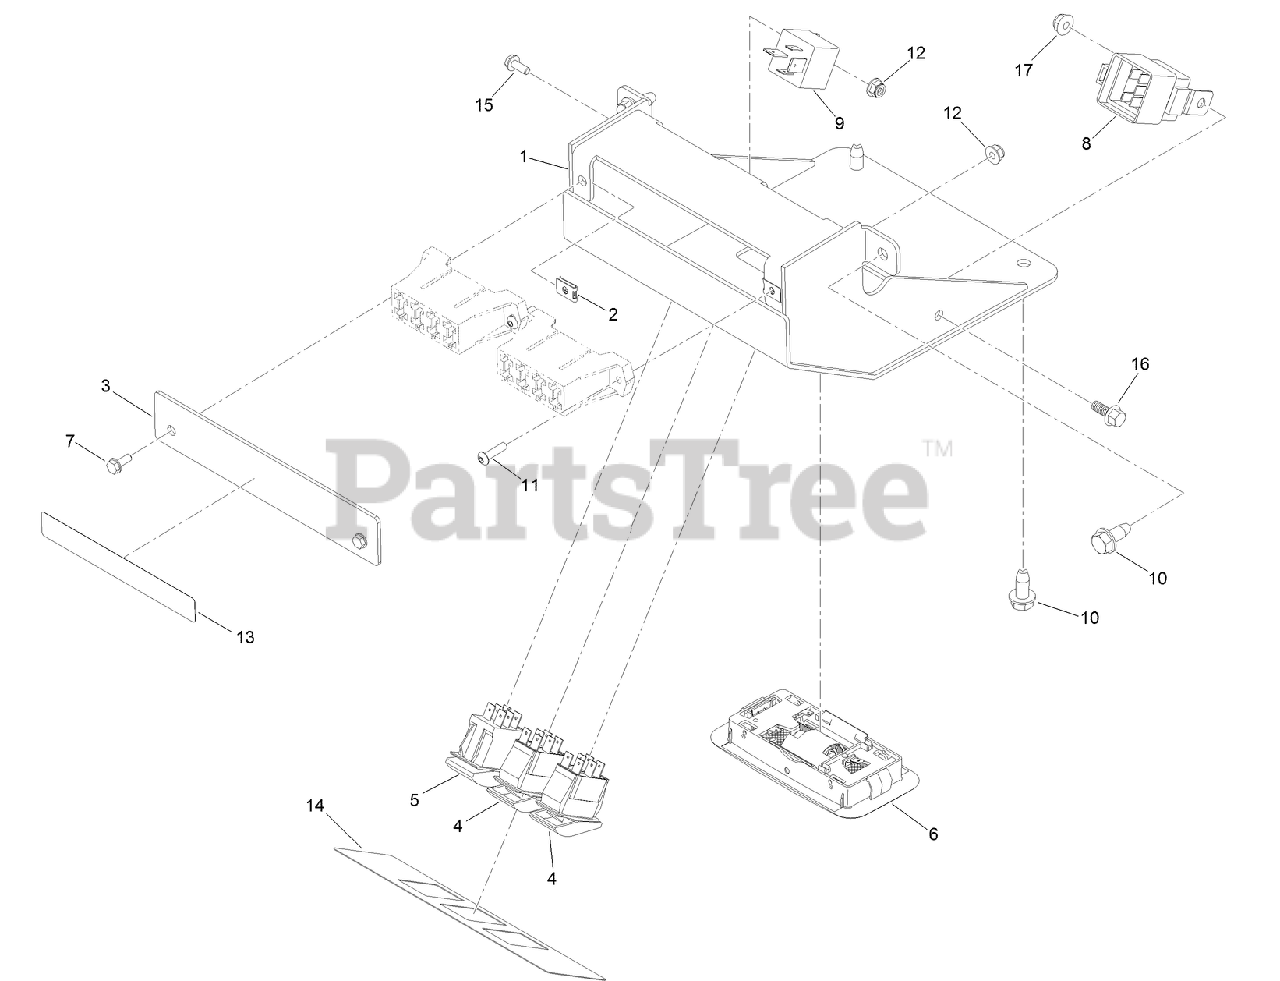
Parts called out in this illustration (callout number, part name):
1	PANEL-CONTROL
2	NUT-SPEED
3	PLATE-ACCESS PANEL, FUSE
4	SWITCH-ROCKER
5	SWITCH
6	LIGHT-DOME
7	SCREW-HWH
8	RELAY-MINI 280
9	RELAY
10	SCREW-HWH
11	SCREW-HSBH
12	NUT-HF
13	DECAL-FUSE BOX
14	DECAL-CONTROLS
15	SCREW-HWH
16	SCREW-HHF
17	NUT-HF
